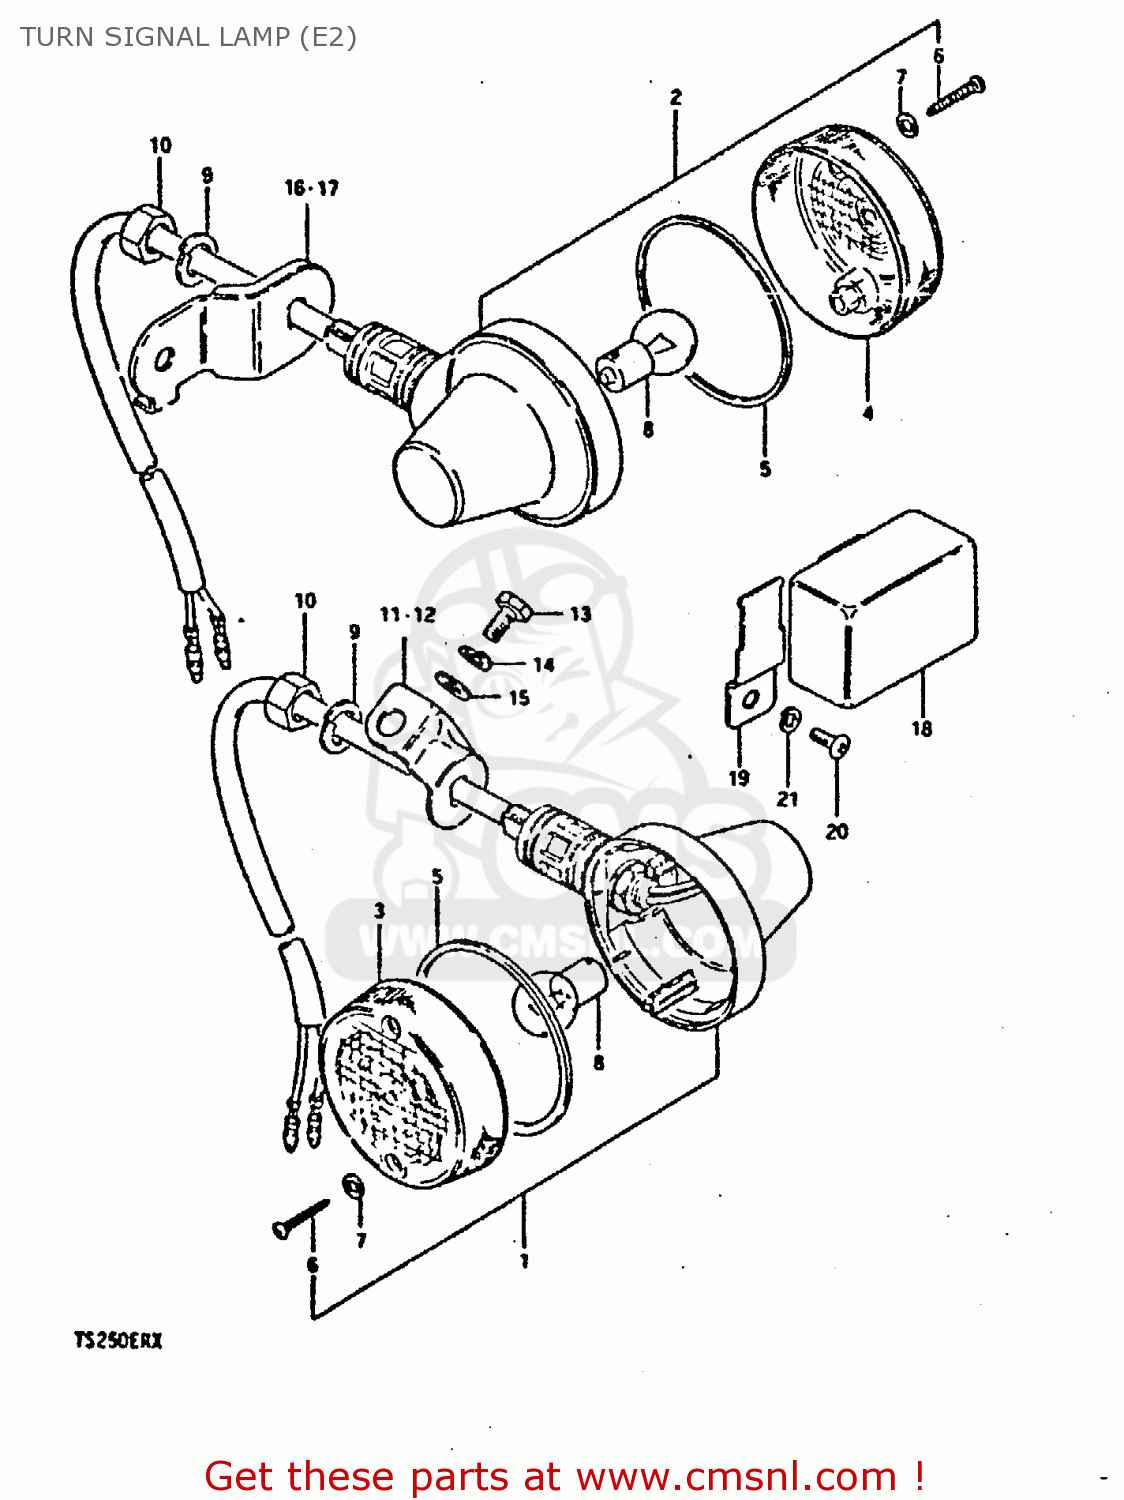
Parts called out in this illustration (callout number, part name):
1	LAMP ASSY,RR TURNSIGNAL
2	LAMP ASSY,RR TURNSIGNAL
3	LENS
4	LENS
5	GASKET (NAS)
6	SCREW TAPP.
7	GASKET (NAS)
8	BULB (6V,18W)
9	WASHER,LOCK 12
10	NUT
11	BRACKET,TURN SIGNAL LAMP
12	BRACKET,TURN SIGNAL LAMP
13	BOLT
14	LOCK WASHER
15	WASHER
16	BRACKET,REAR TURN SIGNAL
17	BRACKET,REAR TURN SIGNAL
18	RELAY,TURN SIGNAL
19	BRACKET,TURN SIGNAL RELAY
20	SCREW 6X12
21	LOCK WASHER
